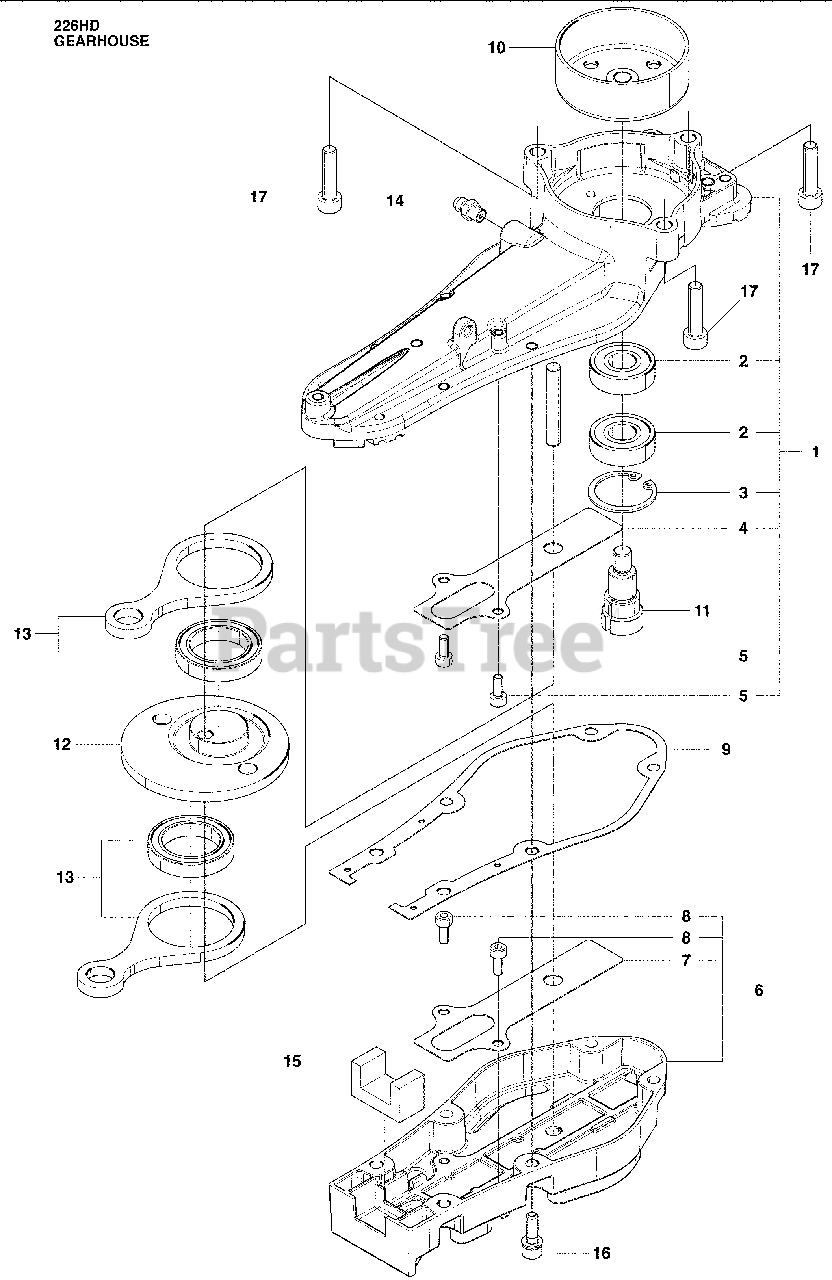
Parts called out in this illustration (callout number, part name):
1	Gear Case, Complete
6	GEARCASE COMP. BOTTOM
11	GEAR DRIVE
12	GEAR DRIVE
13	Rod Assembly
14	Fitting
